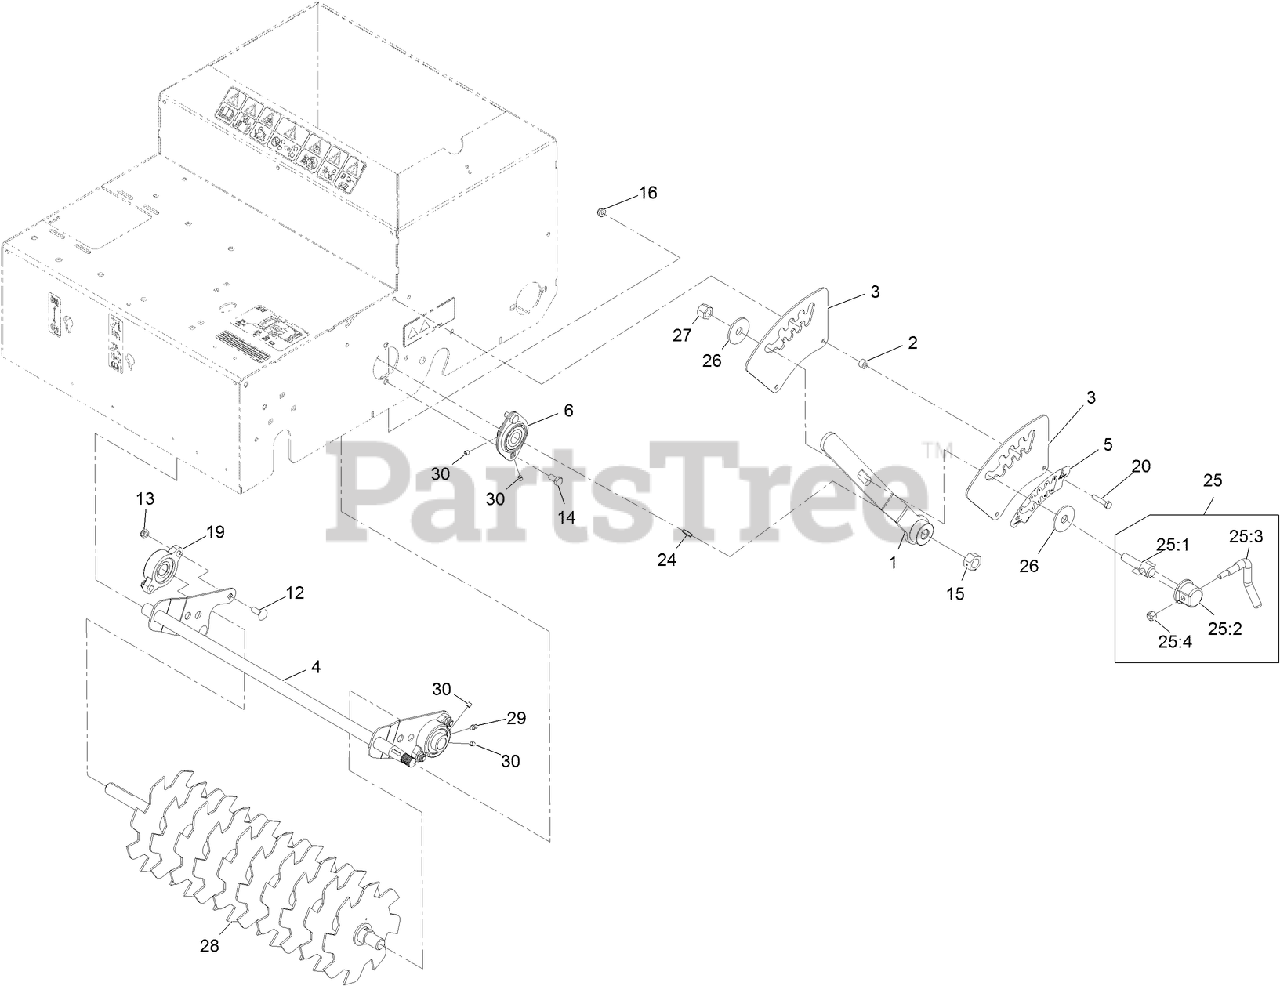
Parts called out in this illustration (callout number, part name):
1	HANDLE-HEIGHT
2	Spacer
3	PLATE-HEIGHT
4	PIVOT-HEIGHT
5	DECAL-CUT DEPTH, SLICER/SEEDER
6	BEARING
12	SCREW-CARR
13	NUT-LOCK, NI
14	SCREW-HH
15	NUT-BLADE
16	NUT-HF
19	BEARING-FLANGE
20	SCREW-HH
24	KEY-WOODRUFF
25	LEVER ASM
25:1	Screw-Lock
25:2	CAP-LOCK
25:3	Lever-Lock
25:4	NUT-LOCK, NI
26	WASHER-THRUST
27	NUT-LOCK, NI
28	SLICER SHAFT ASM
29	FITTING-GREASE
30	SCREW-SET, HSH
